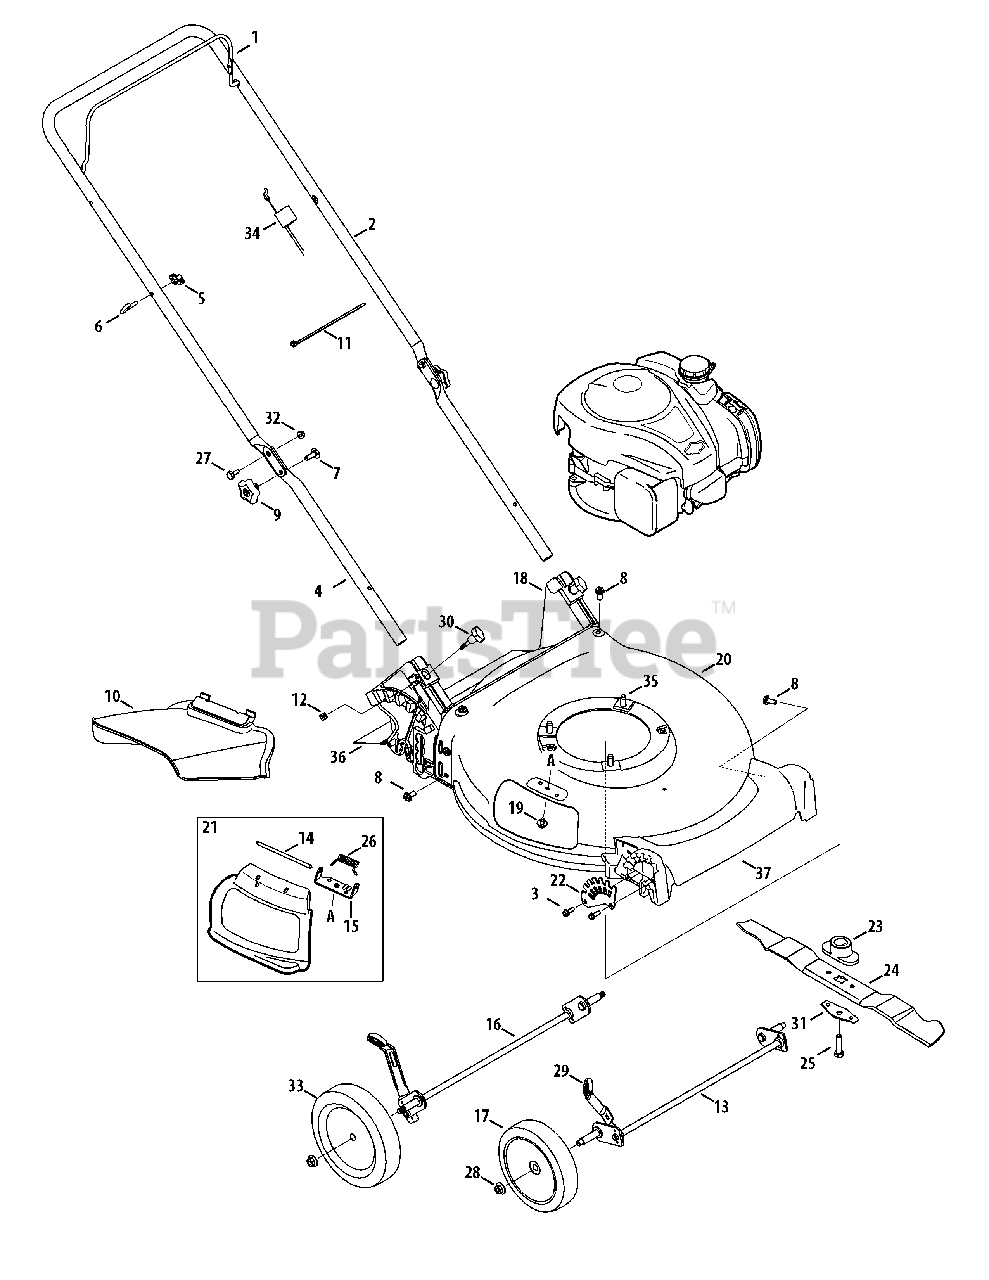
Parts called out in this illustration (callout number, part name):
1	Blade Control
2	Upper Handle
3	Screw, 1/4-15 x .750
4	Lower Handle
5	Wing Nut
6	Rope Guide
7	Carriage Screw ,5/16-18
8	Screw, 5/16-14 x .750
9	Hand Knob
10	Side Chute
11	Cable Tie
12	Nut, Sq., 1/4-20
13	Front Axle Assembly
14	Hinge Pin
15	Chute Deflector Bracket
16	Rear Axle Assembly
17	Wheel, 7 x 1.8
18	Rear Baffle
19	Screw, 1/4-20 x .500
20	Deck - 21"
21	Hinged Mulch Plug Assembly
22	Front Height Adjuster Plate
23	Blade Adapter
24	Mulching Blade
25	Screw , 3/8-24 x 1.50
26	Torsion Spring
27	Sldr. Screw, .375 x .126 x 1/4-20
28	Flange Lock Nut, 3/8-16
29	Adjustment Lever Knob
30	Wing Nut
31	Blade Bell Support
32	Nut, Flange Lock, 1/4-20
33	Wheel, 8 x 1.8
34	Control Cable
35	TT Screw, 3/8-16 x 1.0
36	Trail shield
37	Front Cover
